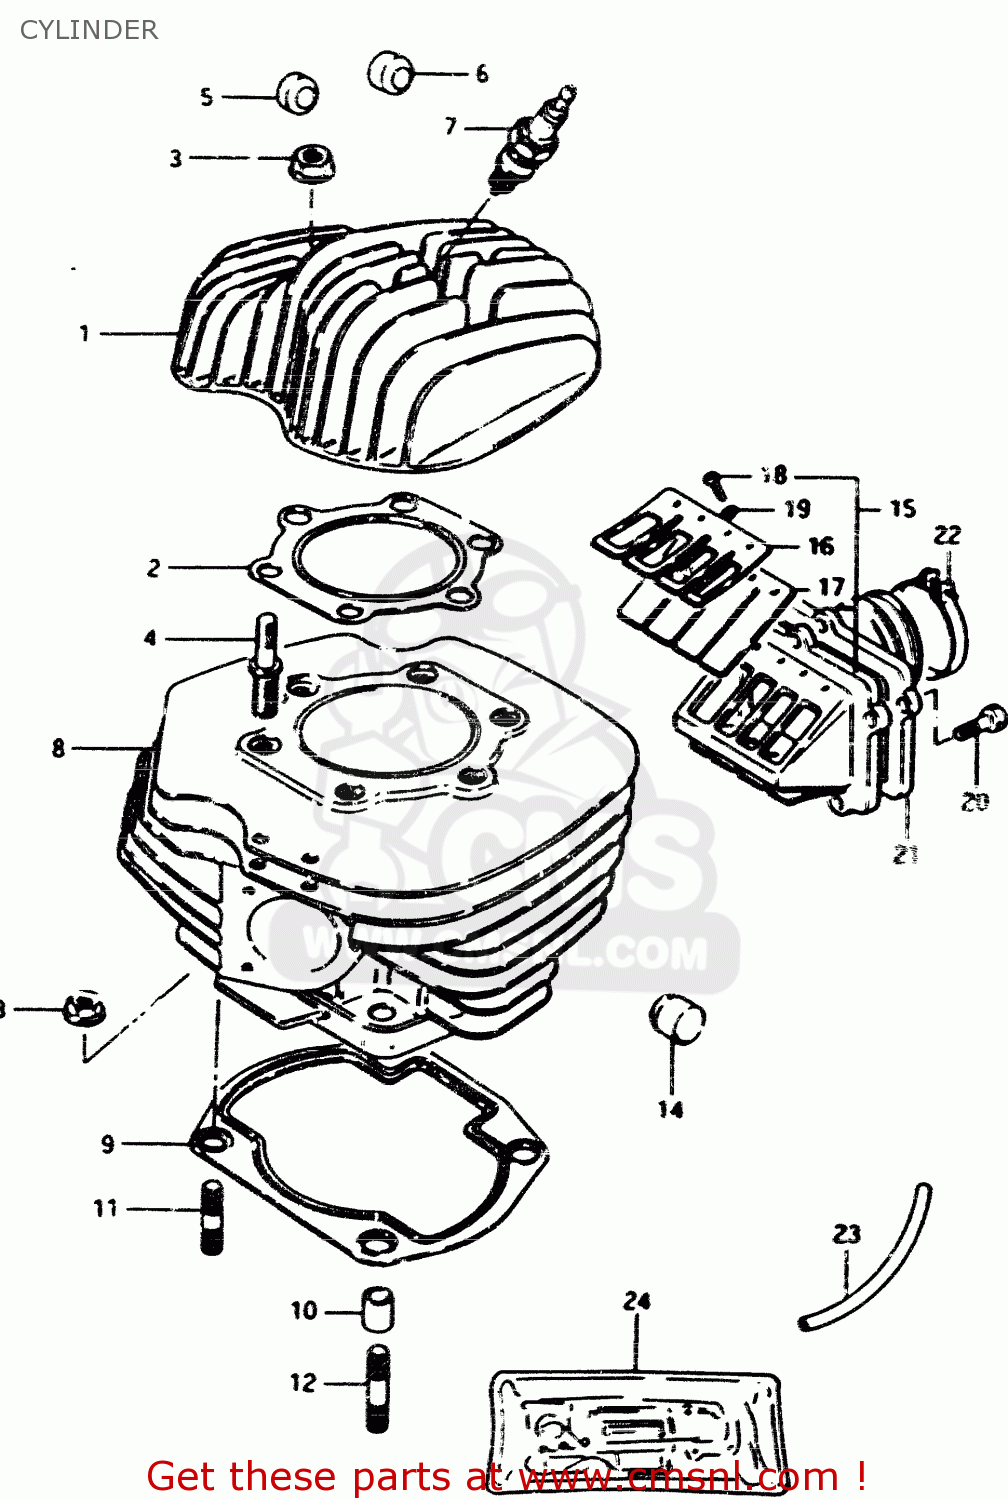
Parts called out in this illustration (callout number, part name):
1	CYLINDER HEAD
2	GASKET,CYLINDER HEAD (NAS)
3	NUT 8MM
4	STUD
5	PAD,CYLINDER
6	PAD,CYLINDER HEAD
7	PLUG,SPARK(NGK B-8EN)
8	CYLINDER
9	GASKET,CYLINDER (MCA)
10	PIN
11	STUD
12	BOLT,STUD L:60
13	NUT
14	PAD,CYLINDER HEAD
15	VALVE ASSEMBLY,REED
16	STOPPER,REED VALVE
17	VALVE,REED
18	SCREW
19	LOCK WASHER
20	BOLT
21	PIPE,INTAKE
22	CLAMP
23	HOSE
24	GASKET
